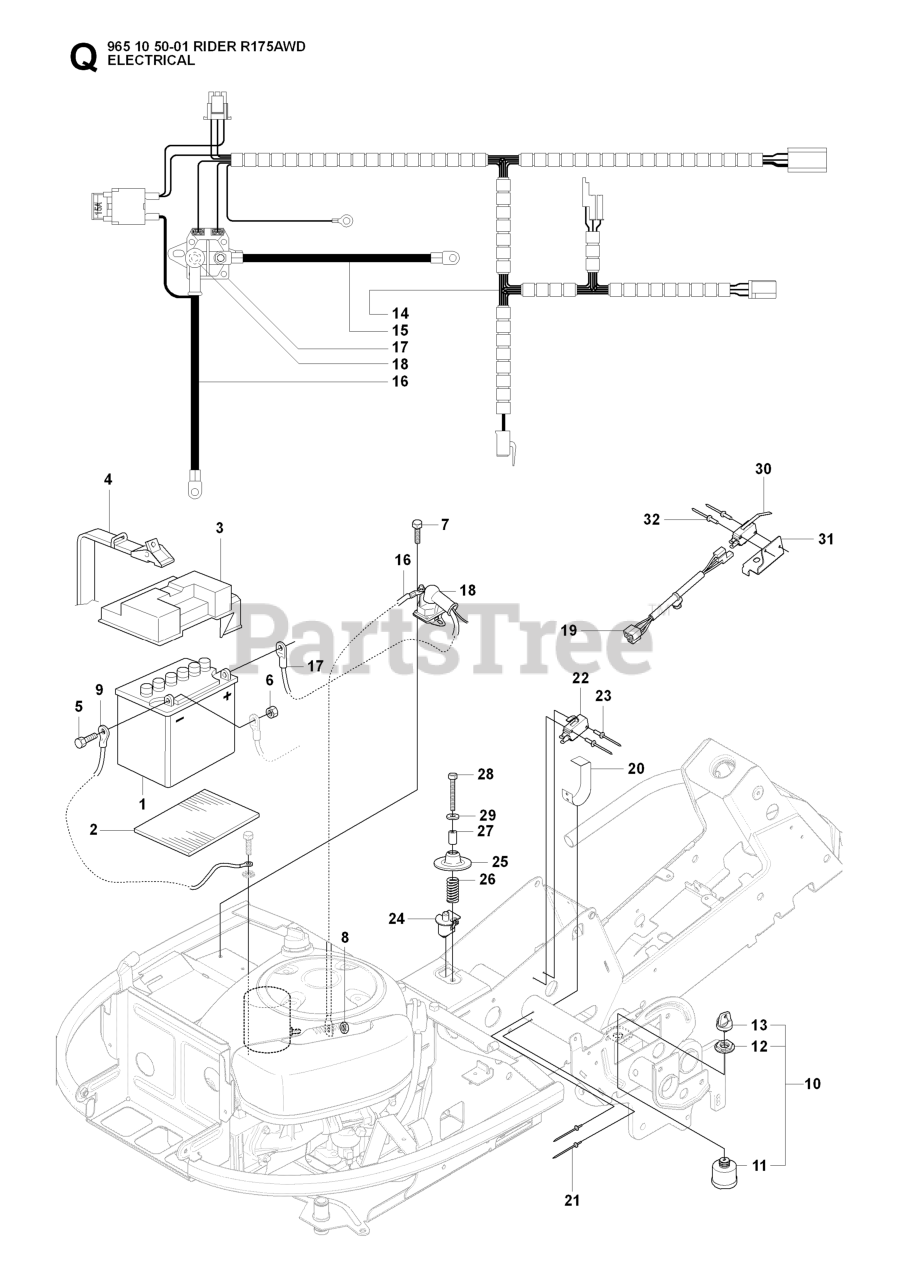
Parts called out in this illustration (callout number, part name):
1	BATTERY - DRY
10	IGNITION SWITCH
11	IGNITION SWITCH
13	IGNITION KEY
19	WIRING
22	%BRAKER
27	SPACER TUBE
28	SCREW
29	WASHER BRB 8.4X17
30	RP MICRO SWITCH
